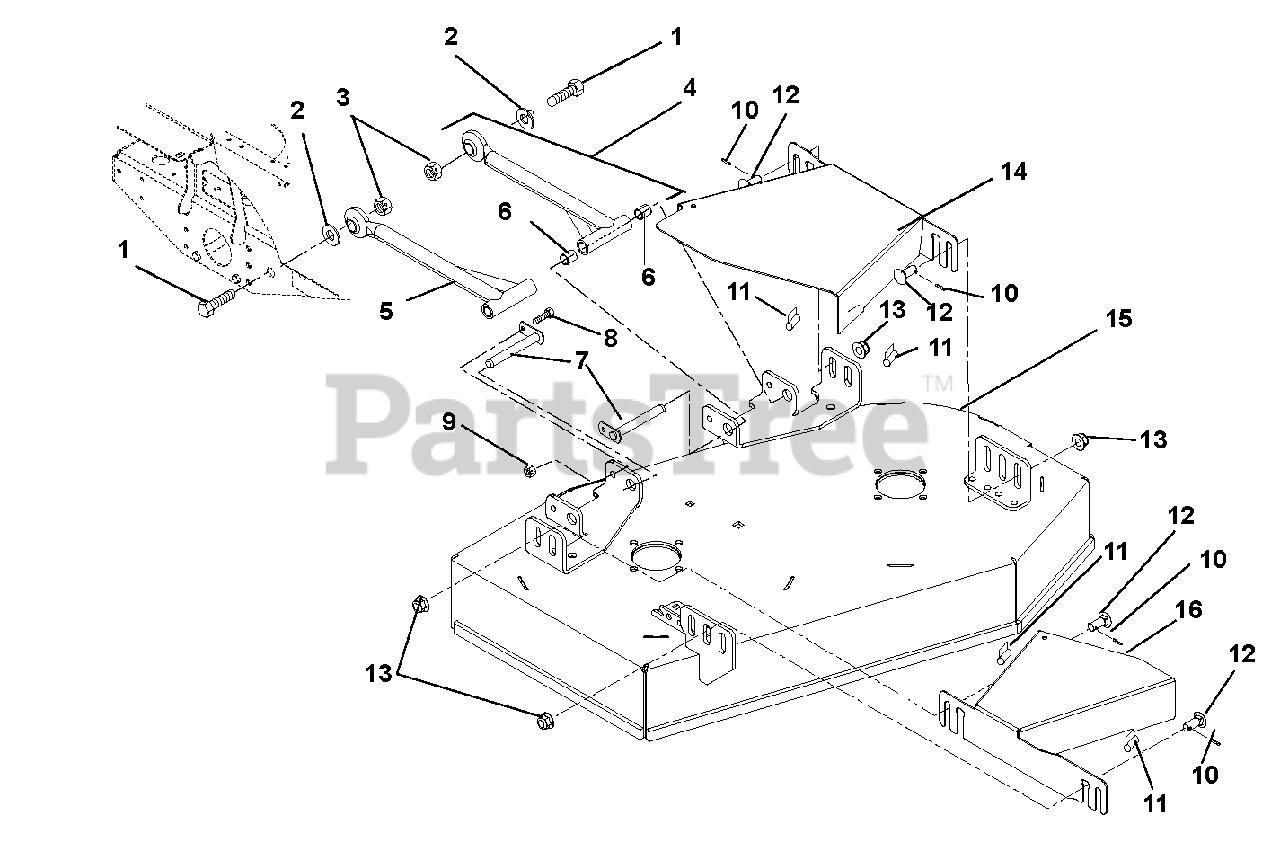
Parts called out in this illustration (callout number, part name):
1	Bolt, Hex .875-9 x 3.00
2	Bushing, Sleeve .875 x 1.25 x .531
3	Nut, Locking Center .875-9
4	Assembly, Mower Mounting (Includes Items 5 and 6)
5	Arm, Mower Mounting
6	Bearing, .75 x .875 x 1.00
7	Weldment, Mower Mounting Pin
8	Bolt, Hex .38-16 x 1.00
9	Nut, Nyloc Flange 3/8-16
10	Pin, Roll .125 x .75
11	Seal, Trim-LOK Bulk .06 Bubble
12	Bolt, Round Head Square Neck .50-13 x 1.25 SPL
13	Nut, Nyloc Flange .50-13
14	Guard, 34" Belt, CE, Black
15	Weldment, 34" Mower Deck, Rear Discharge
16	Weldment Belt Guard 34" RH
